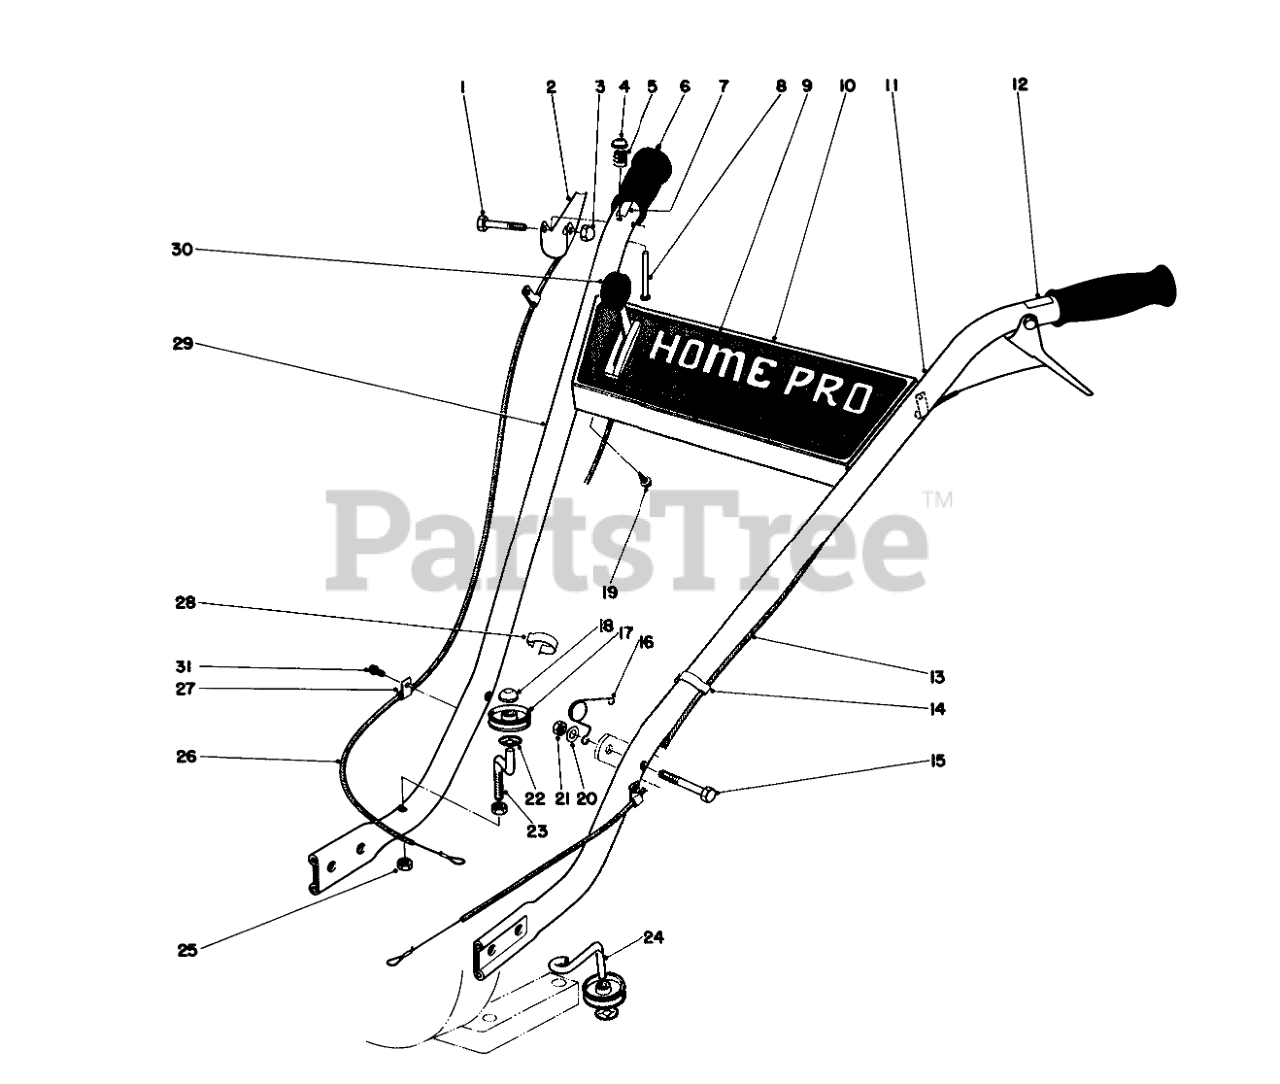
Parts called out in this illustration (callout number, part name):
1	SCREW-HH
2	LIFTBAIL
3	NUT-CAP
4	Push-On
5	COMPRESSION SPRING
6	Hand Grip
7	Decal-Fwd.
8	LOCK PIN
9	Decal-Escutcheon
10	Escutcheon Panel
11	Handle L.H.
12	Decal Rev.
13	REV CABLE ASM
15	SCREW-HH
16	Spring-Torsion
17	Pulley Cable
18	216 Washer
19	SCREW-HWHTF
20	WASHER-PLAIN
21	NUT-LOCK, CONE
22	PUSH ON RETAINER
23	Spindle-Fwd.
24	Spindle-Rev.
25	LOCKNUT
26	FWD CABLE ASM
27	3/16 SUPPORT
28	Boden Clip
29	RH HANDLE
30	THROTTLE CONTROL
31	10 X 1/2 SCREW
